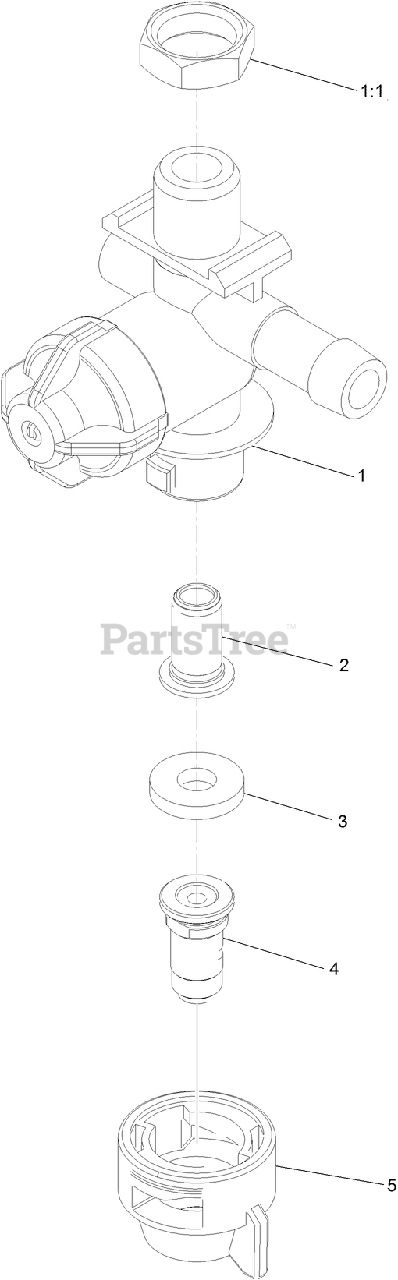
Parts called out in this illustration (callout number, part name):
1	LH NOZZLE BODY ASM
1:1	NUT-NYLON
2	STRAINER-TIP
4	NOZZLE-SPRAY, WHITE
5	CAP-NOZZLE
99	NOZZLE-SPRAY, BLUE
99	NOZZLE-SPRAY, BROWN
99	NOZZLE-SPRAY, GRAY
99	NOZZLE-SPRAY, RED
